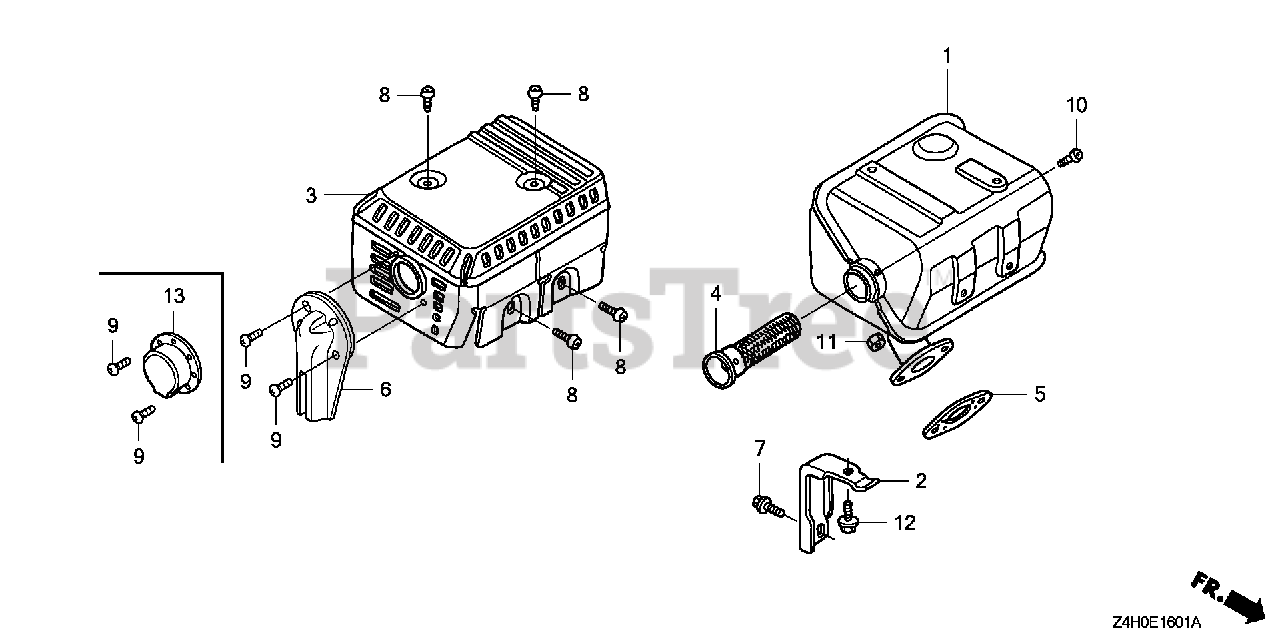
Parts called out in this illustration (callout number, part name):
1	MUFFLER (SILENT)
1	MUFFLER (ARRESTER)
2	STAY, MUFFLER
3	PROTECTOR, MUFFLER (SILENT)
4	ARRESTER, SPARK
4	ARRESTER, SPARK (SILENT)
5	GASKET, MUFFLER
7	BOLT, FLANGE (6X13) (CT200)
8	SCREW, TAPPING (5X8)
9	SCREW, TAPPING (4X6)
10	SCREW, TAPPING (4X6)
11	NUT, HEX. (8MM)
12	BOLT, FLANGE (6X12)
13	CAP, MUFFLER
